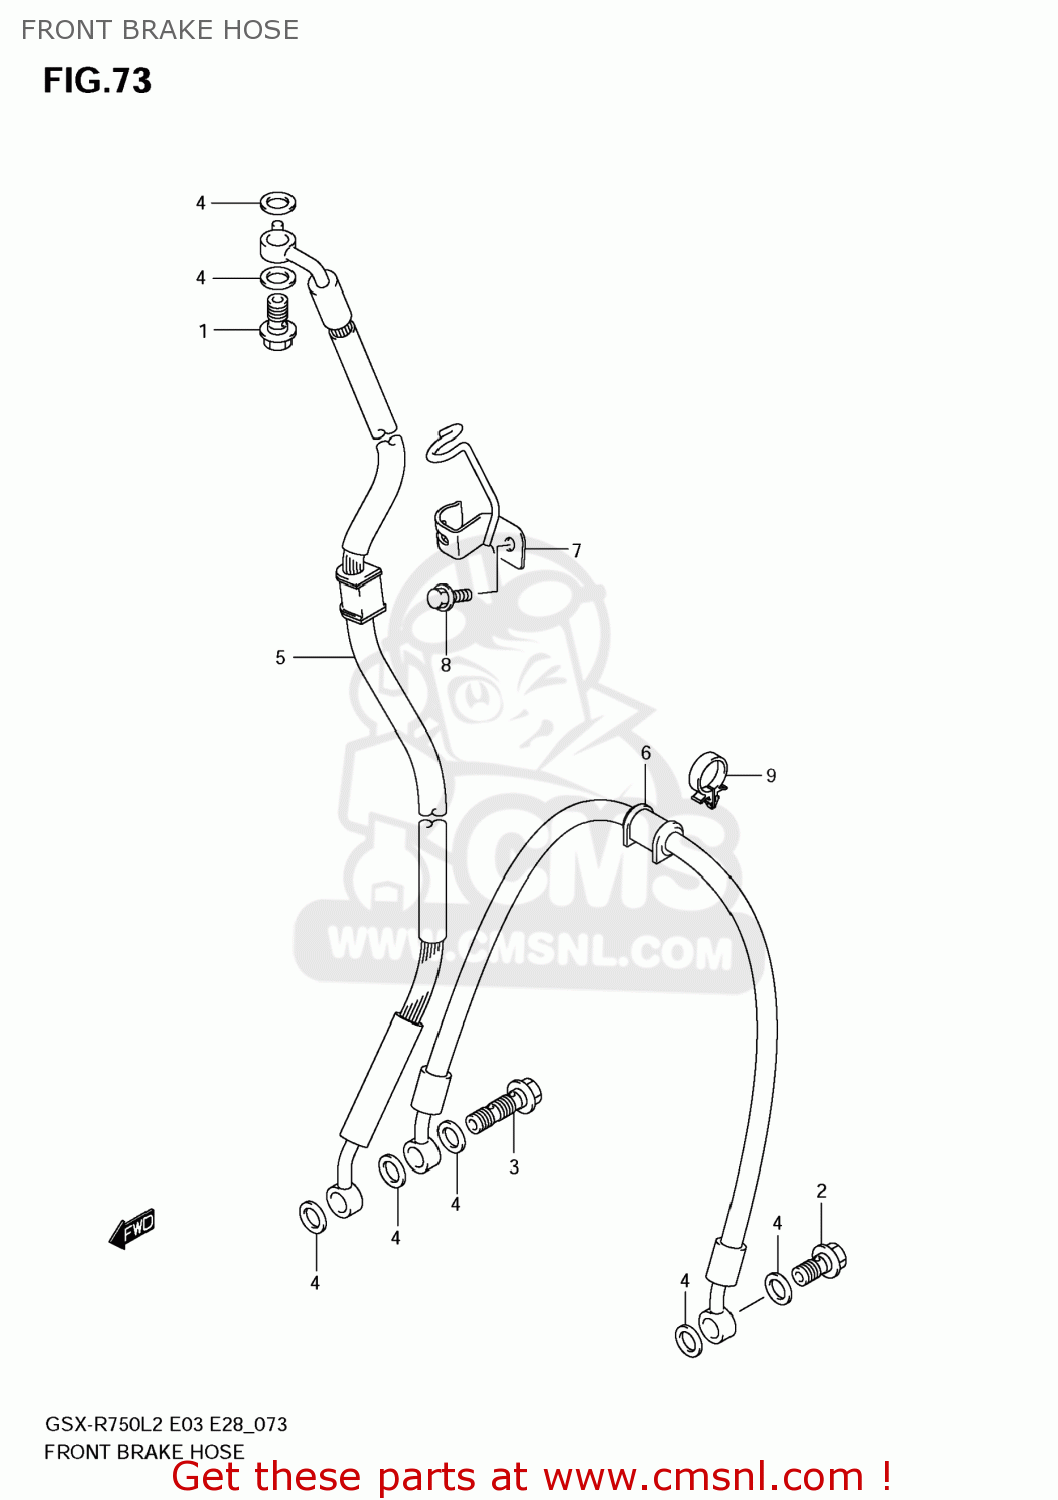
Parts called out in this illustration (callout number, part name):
1	BOLT UNION
2	BOLT UNION
3	BOLT UNION
4	WASHER(10X15X1.5)
5	HOSE,FR BRAKE NO.1
6	HOSE,FR BRAKE NO.2
7	CLAMP,FR BRAKE HOSE NO.1
8	BOLT
9	CLAMP
